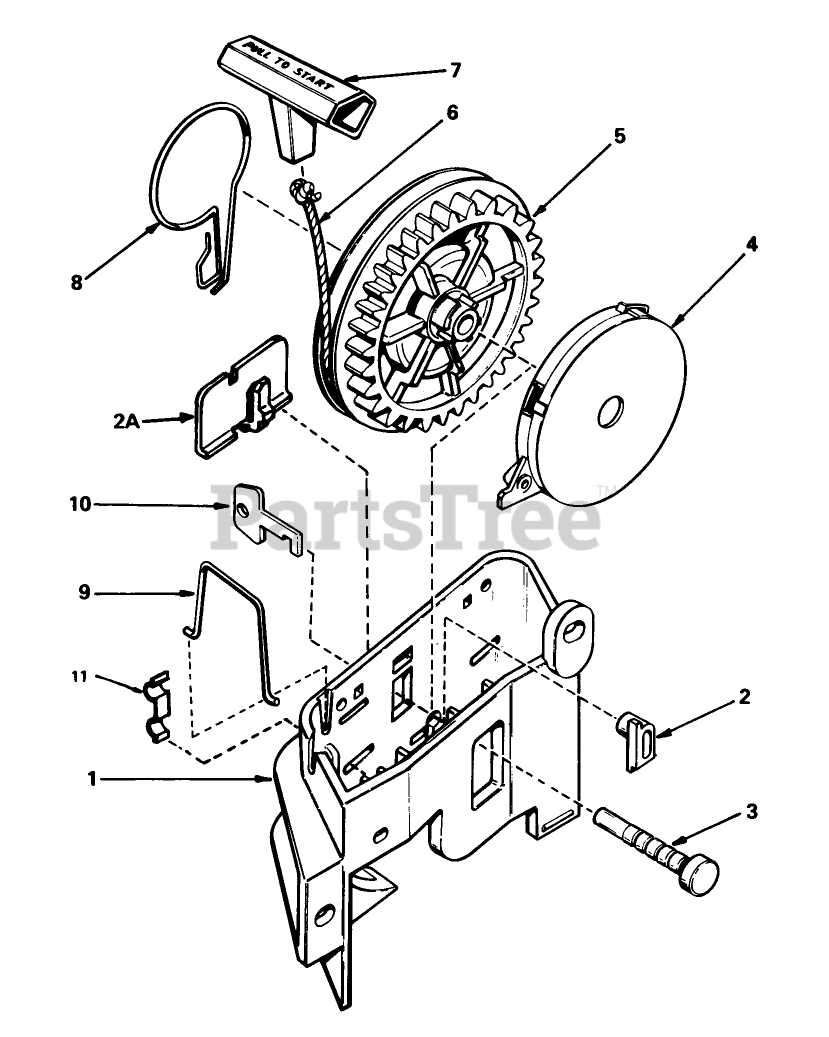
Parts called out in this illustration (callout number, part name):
1	Bracket Starter
2	Pawl, Locking Not used on all engine models)
2A	Clip, Starter Bracket (Used On Starters Not Equipped With Pawl, Ref. No. 2)
3	Pin-Pulley
4	Spring Assy., Rewind (Incl. Ref. #3)
5	Pulley
6	Rope Starter (Length 65" 9/64" Dia.)
7	Handle-Starter
8	Brake
9	Clip-Rope
10	Key (Not Used On All Engine Models
11	Washer-Thrust
